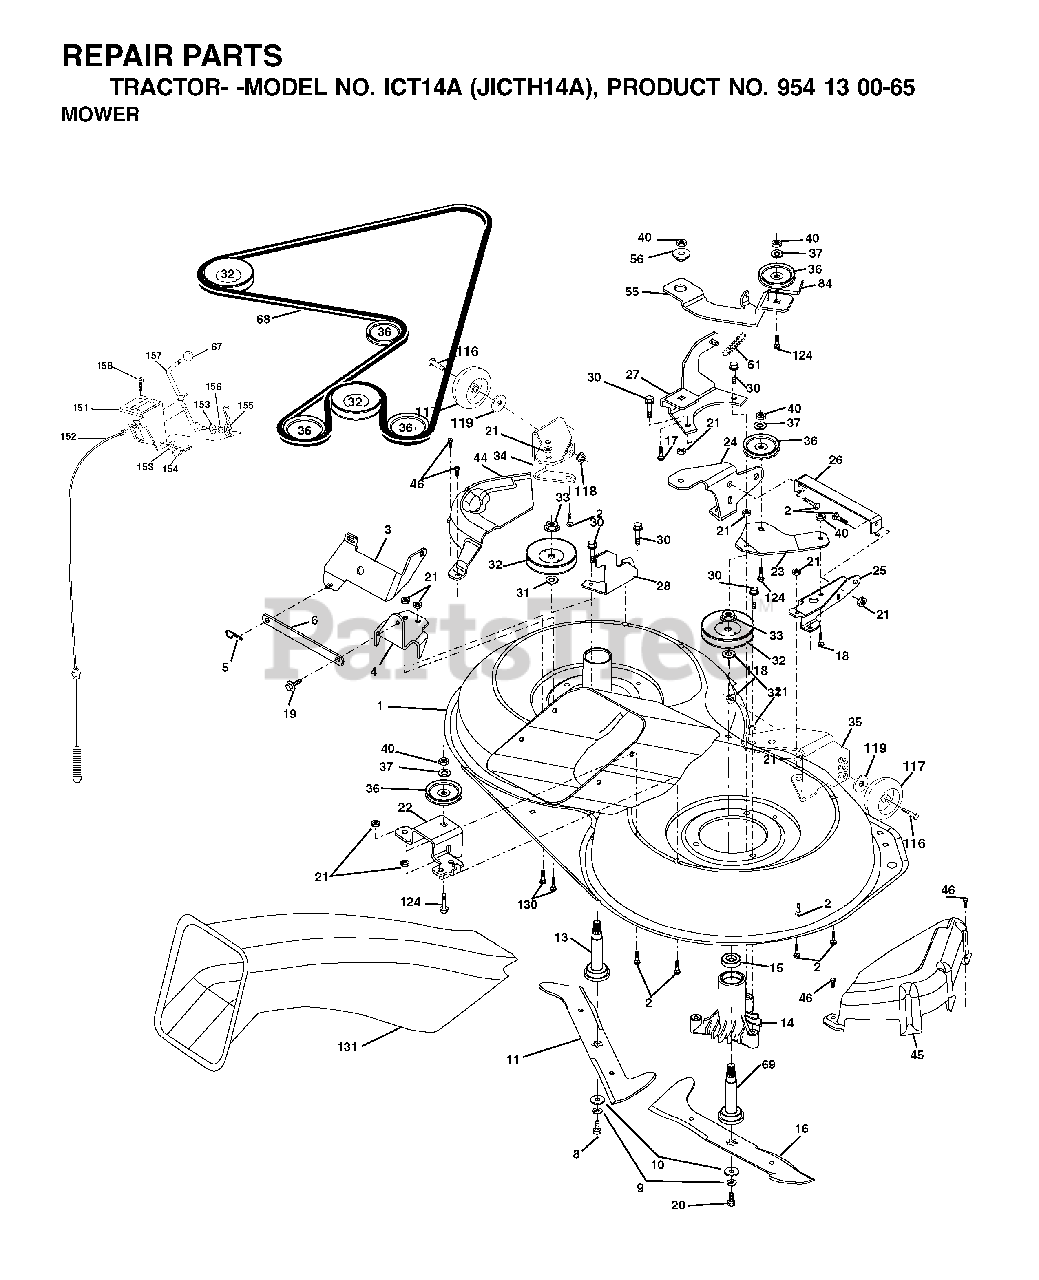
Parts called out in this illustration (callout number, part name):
1	MOWER HOUSING, DECK
2	BOLT
3	BRACKET
5	RETAINER-SPRNG RB
6	BAR SWAY
8	BLADE BOLT
9	LOCKWASHER
10	WASHER.BLADE
11	BLADE-LH 5PT STAR(CTH130)
13	SHAFT ASM VENT
14	HSG MANDREL
16	BLADE RH 6PT STAR(CTH130)
17	BOLT.3/8-14X1.25
19	BOLT SHD 5/16-18
21	LOCKNUT
24	BRACKET
25	BRACKET
26	BRACE
28	BRACKET
30	SCREW, WASHER HEAD
31	WASHER
32	PULLEY, MANDREL
33	NUT, FLG TOPLOCK 9/16"
36	PULLEY.IDLER.4.25
40	LOCKNUT
45	MANDREL COVER
46	SCREW.1/4-20X5/8
55	ARM IDLER
56	SPACER.RETAINER.MOWER
61	SPRING.TENSION.BELT
67	KNOB T (3/8 HOLE)
68	HEX-BELT 92 MOWER 105AA
69	SHAFT.ASM.W/LWR.BRG.RH.THREAD
84	KEEPER, BELT IDLER
116	BOLT, SHOULDER
117	WHEEL GAGE DONUT
118	LOCKNUT
119	WASHER
124	BOLT.3/8-16X1.50
131	CHUTE BAGGER
151	BRACKET, CLUTCH CABLE
153	WASHER FLAT 3/8"
154	SPRING RETAINER
155	SPRING RETENTION LEVER
156	SPACER CLUTCH CABLE
157	ROD CLUTCH CABLE 3/8"
158	SCREW
